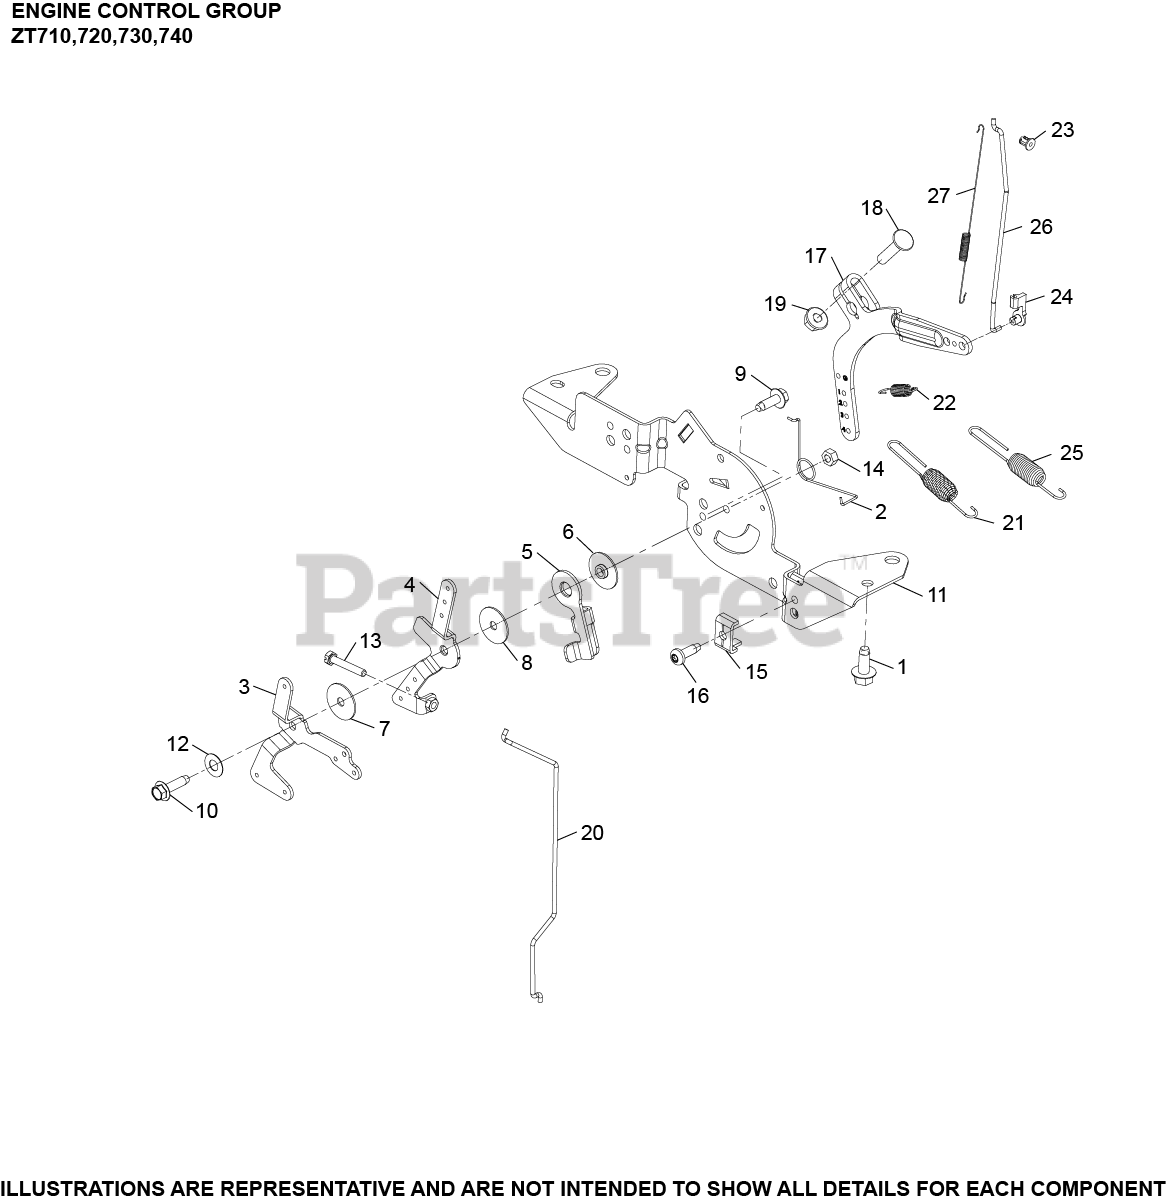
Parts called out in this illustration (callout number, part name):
1	SCREW, THREAD FORMING
2	SPRING, CHOKE RETURN
3	LEVER, CHOKE
4	LEVER, THROTTLE CONTROL
5	LEVER, THROTTLE ACTUATOR
6	SPACER, CONTROL ASSEMBLY
7	WASHER, FLAT 5.5 MM
8	WASHER, FLAT 5 MM
9	SCREW, THREAD FORMING
10	SCREW, THREAD FORMING - USE 25 086 473-S
11	BRACKET, CONTROL USE 32 126 18-s
12	WASHER, SPRING 1/4"
13	SCREW, SLT HD CAP M4X0.7X25
14	NUT, LOCK M5X.8
15	CLAMP, CABLE
16	SCREW, THREAD FORMING
17	LEVER, GOVERNOR - (#2409069S)
18	BOLT, RD HD SQ NECK M6X1.0X25
19	NUT, FLG M6X1.0
20	LINKAGE, CHOKE
22	SPRING, GOVERNED IDLE
23	BUSHING, LINKAGE RETAINING
24	BUSHING, THROTTLE LINKAGE
25	SPRING, GOVERNOR (ORANGE)
26	LINKAGE, THROTTLE USE 24 079 04-S
27	SPRING, LINKAGE USE 32 089 11-S
